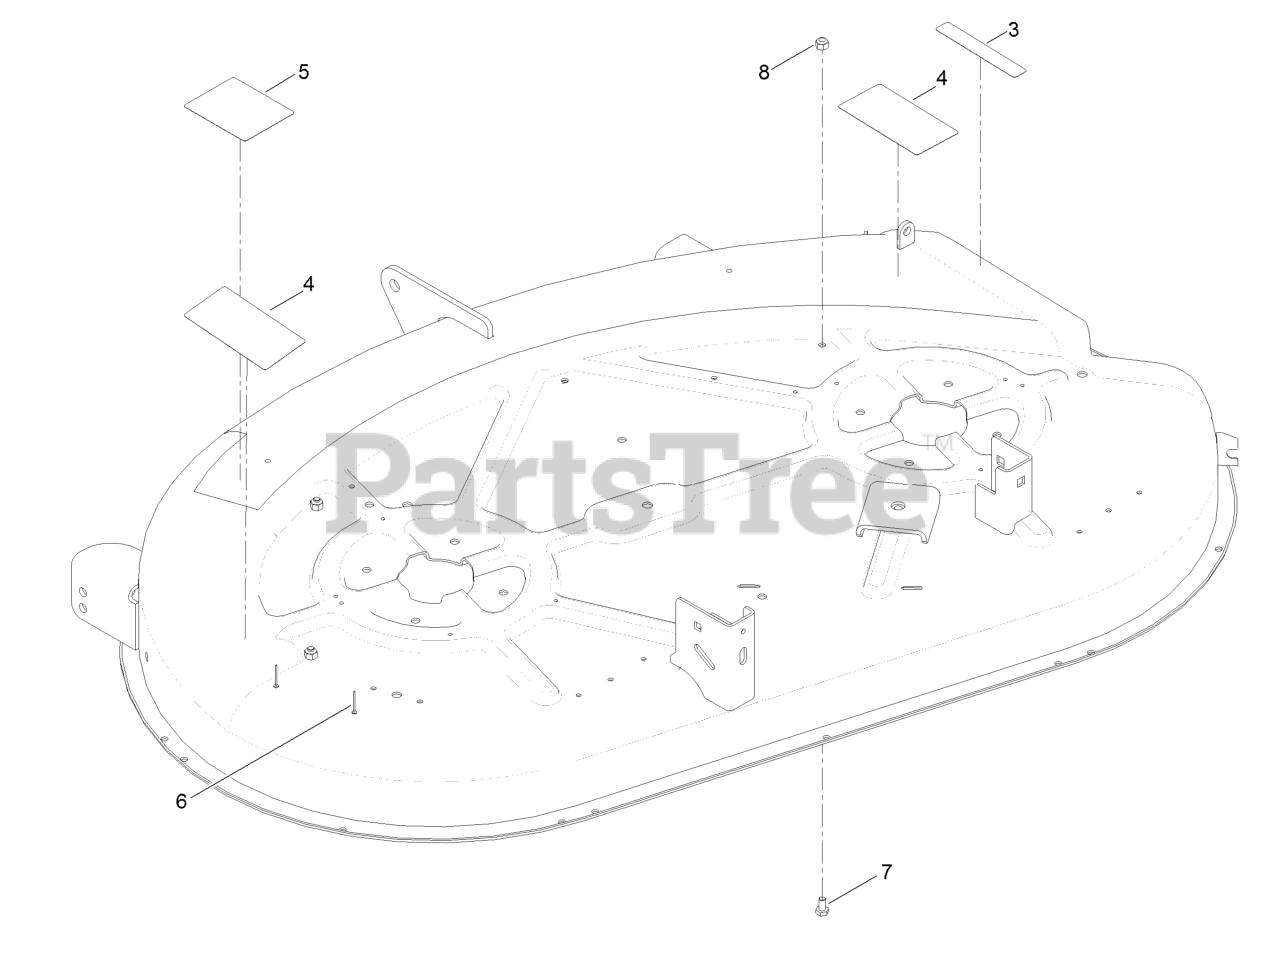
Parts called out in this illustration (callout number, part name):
3	DECAL-DANGER
4	DECAL-DANGER, DECK
5	DECAL-ROUTING, BELT
6	RIVET-BLIND
7	SCREW-HH
8	NUT-LOCK, NI
